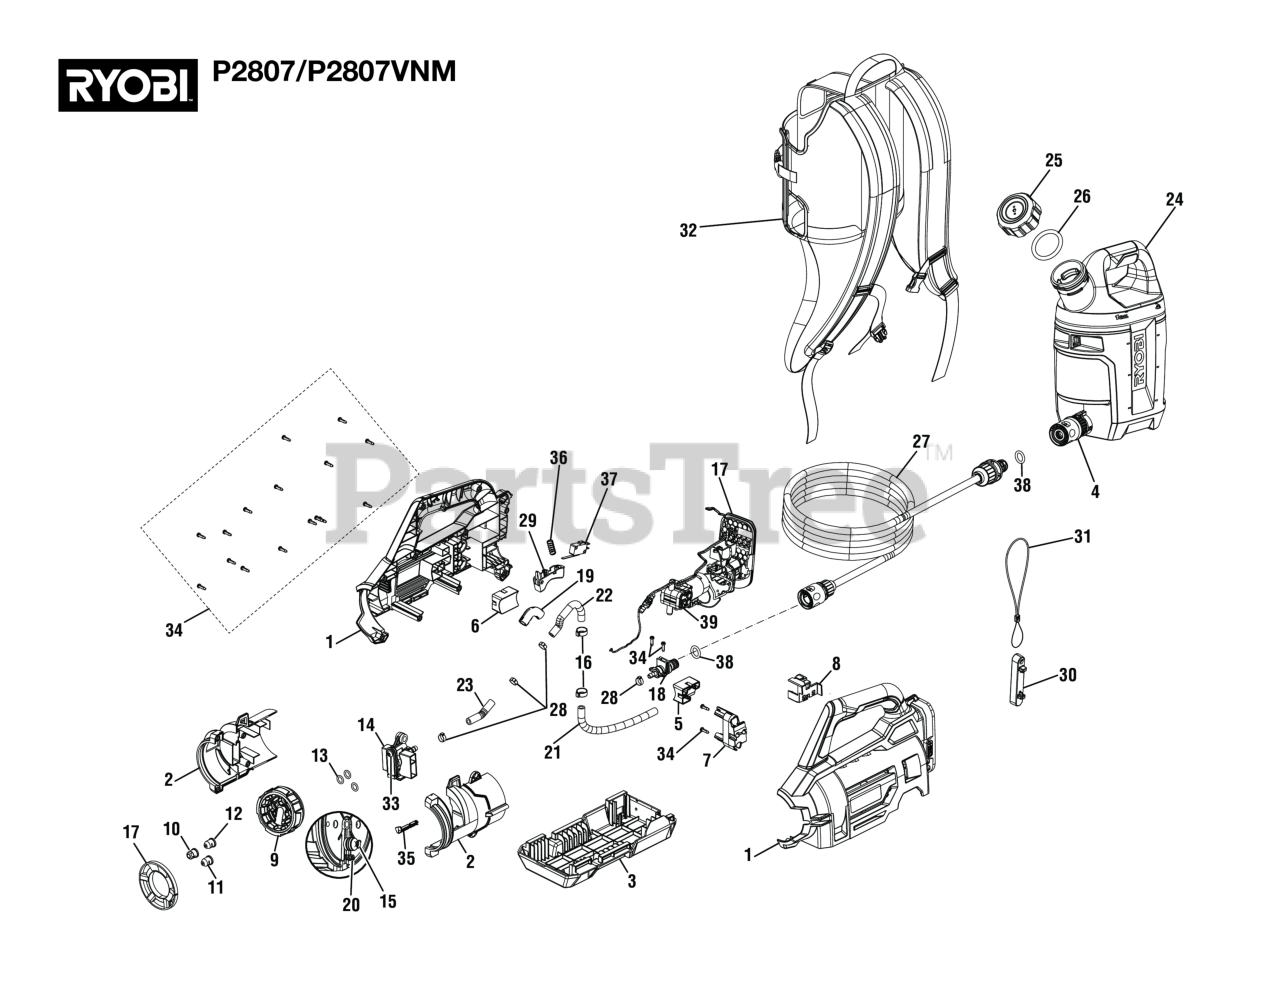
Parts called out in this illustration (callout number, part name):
1	Housing Assembly (Inc. Labels)
2	Outlet Tube Assembly (Inc. Label)
3	Bottom Plate Assembly (Inc. Label)
4	Shut-off Valve
5	Left Motor Support
6	Right Motor Support
7	Base for Pump
9	Nozzle Dial Assembly (Inc. Labels)
10	Low Spray Nozzle Assembly
11	Medium Spray Nozzle Assembly
12	High Spray Nozzle Assembly
14	Nozzle Body Assembly
15	Piston Seal Assembly
17	Motor & Battery Foot Assembly
18	Male Quick Connect
19	Pipe Shroud Assembly
20	Ball and Spring Assembly
21	Tube (Pump Inlet)
22	Tube (Pump Outlet)
23	Tube (Barb Nozzle)
24	Tank Assembly
27	Hose Assembly
29	Switch Trigger
30	Nozzle Wrench
32	Tank Holster
33	Screw (M5)
34	Screw (M4 x 14 mm, T15 Torx Pan Hd.))
35	Wire Cover
36	Compression Spring
38	O-Ring (ID11.3 x CS2.5)
39	Motor & Pump Assembly
